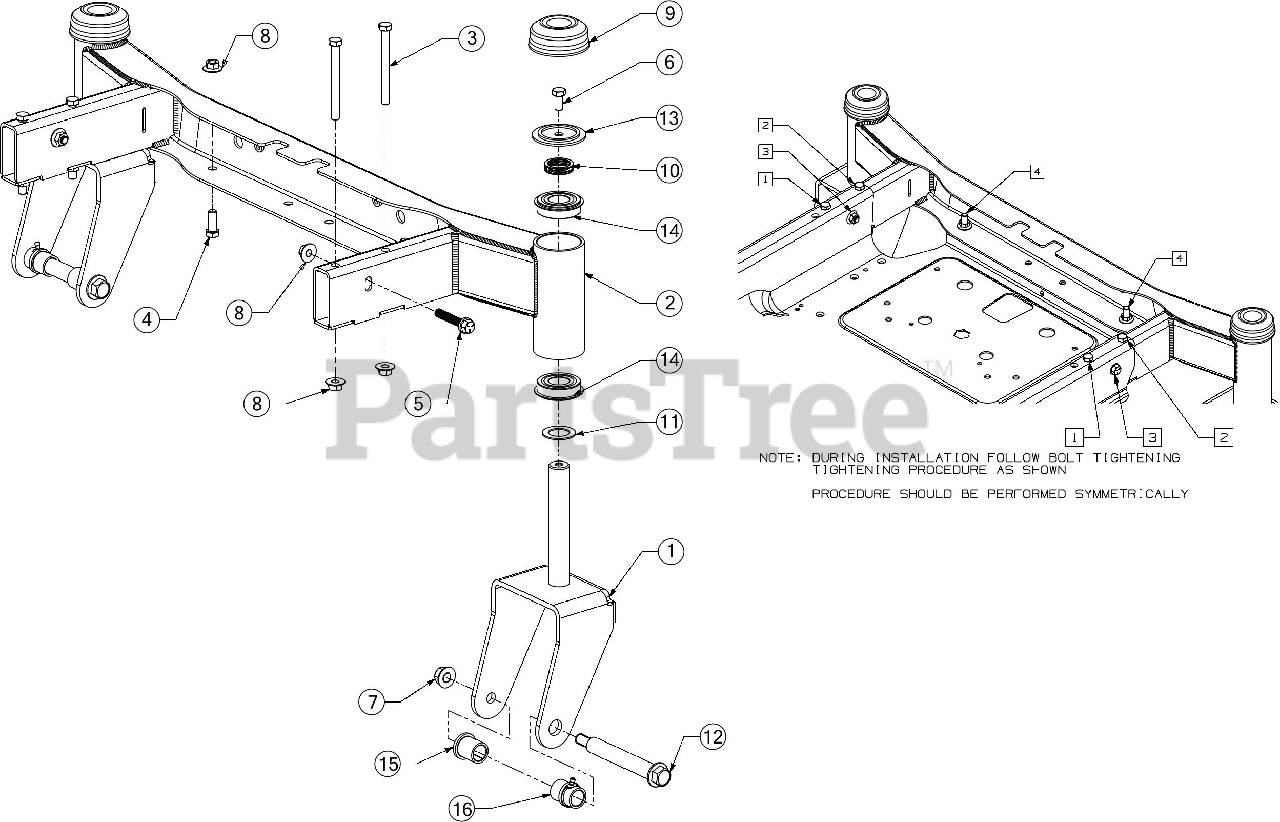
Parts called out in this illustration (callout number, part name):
1	CASTER WHEEL YOKE
2	FRONT AXLE ASSEMBLY
3	SCREW 3/8-16 x 3.75 GR5
4	SCREW 3/8-16 x 1 GR5
5	SCREW 3/8-16 x 2.00 GR5
6	SCREW 3/8-16 x .75 GR 5
8	FLANGE LOCK NUT
9	CASTER AXLE CAP
10	WAVE WASHER
11	WASHER 1.010X1.560X.060
12	SHOULDER BOLT 1.00X4.75X1/2-13
13	SHOULDER SPACER
14	BALL BEARING
15	FLANGE BEARING
16	FLANGE BEARING W/ZERK FITTING
